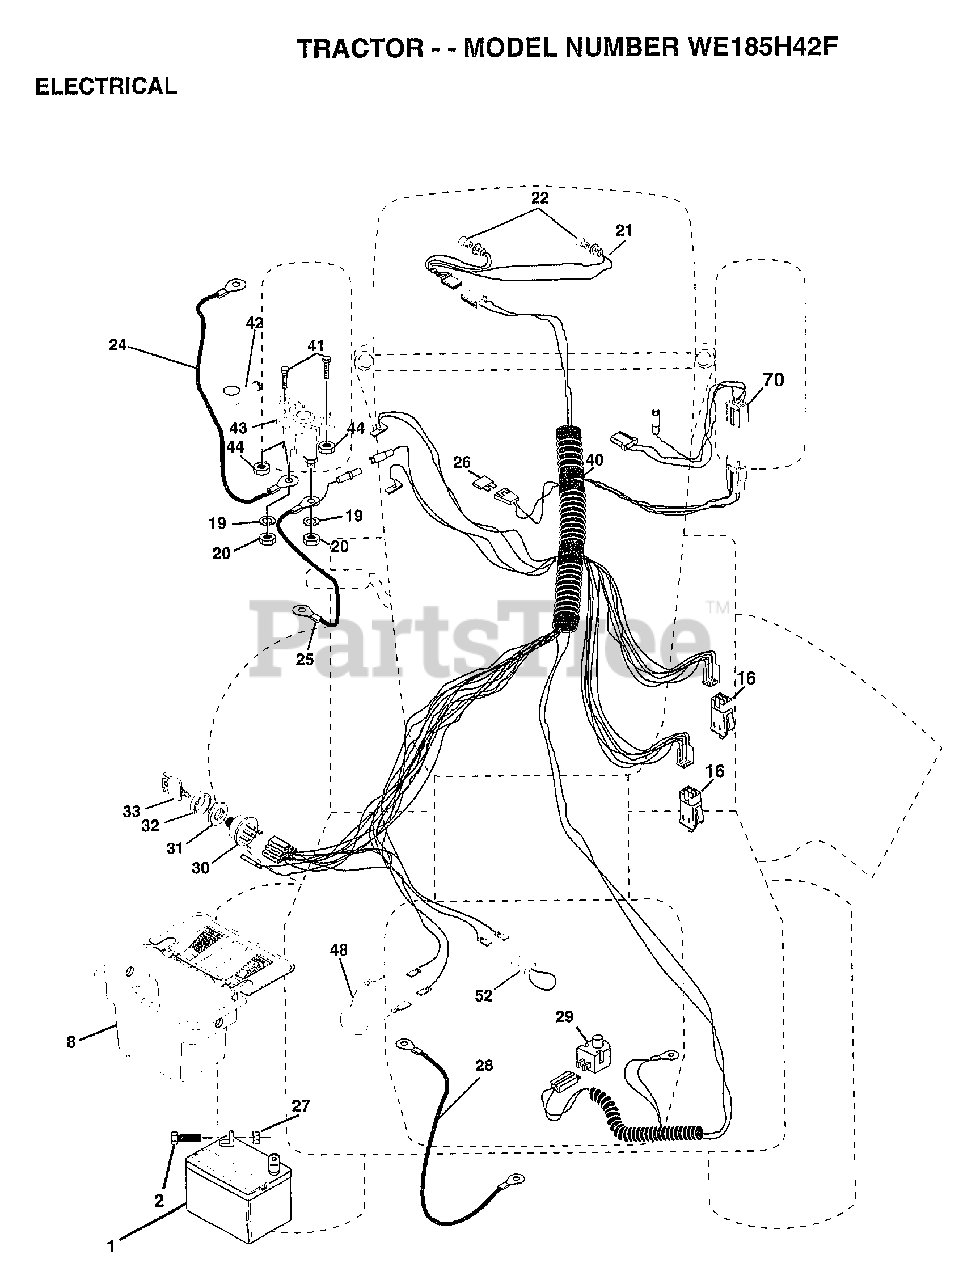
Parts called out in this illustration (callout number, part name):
2	BOLT LT
8	"CASE,BATTERY.MECH"
16	SWITCH INTERLOCK
20	NUT
21	HARNESS.ASM.LIGHT W/4152J
22	HEADLAMP BULB
24	"CABLE T, BATTERY"
25	CABLE.BTRY.6GA.RD
26	FUSE.15 AMP
27	NUT
28	CABLE T
29	SWITCH SEAT
30	SWITCH IGN 4POS
31	NUT IGNITION
32	COVER KEY SWITCH
33	KEY
40	HARNESS.IGNITION
41	BOLT HXHD FIN
44	NUT HXKEP 1/4X20
48	ADAPTER AMMETER
52	PROTECTION LOOP
70	HARNESS.ENGINE
